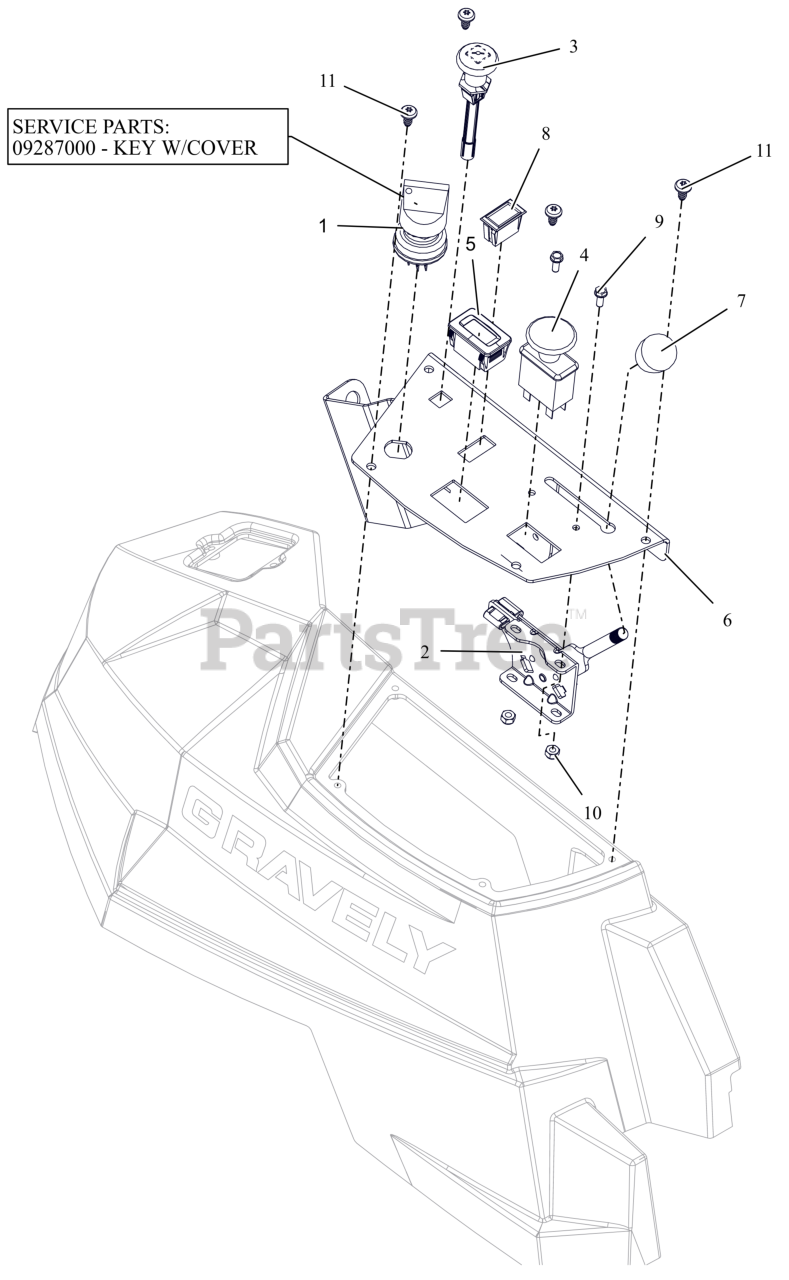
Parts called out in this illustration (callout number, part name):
1	SWITCH, IGNITION
1	KEY, W/ SHIELD
2	CABLE, PRO THROTTLE CONTROL
3	CABLE - CHOKE, SNAP-IN
4	SWITCH, CLUTCH
5	HOUR METER
6	PANEL, HD CONTROL
7	KNOB-CONTROL-BLACK .38-16X.50
8	SWITCH,BLANK
9	BLT, HWH #10-24X.50 ZCC
10	NUT-LK-NYL #10-24 G2 ZCC
11	SCR-PAN .25-15X.50 6L H/LZB500
